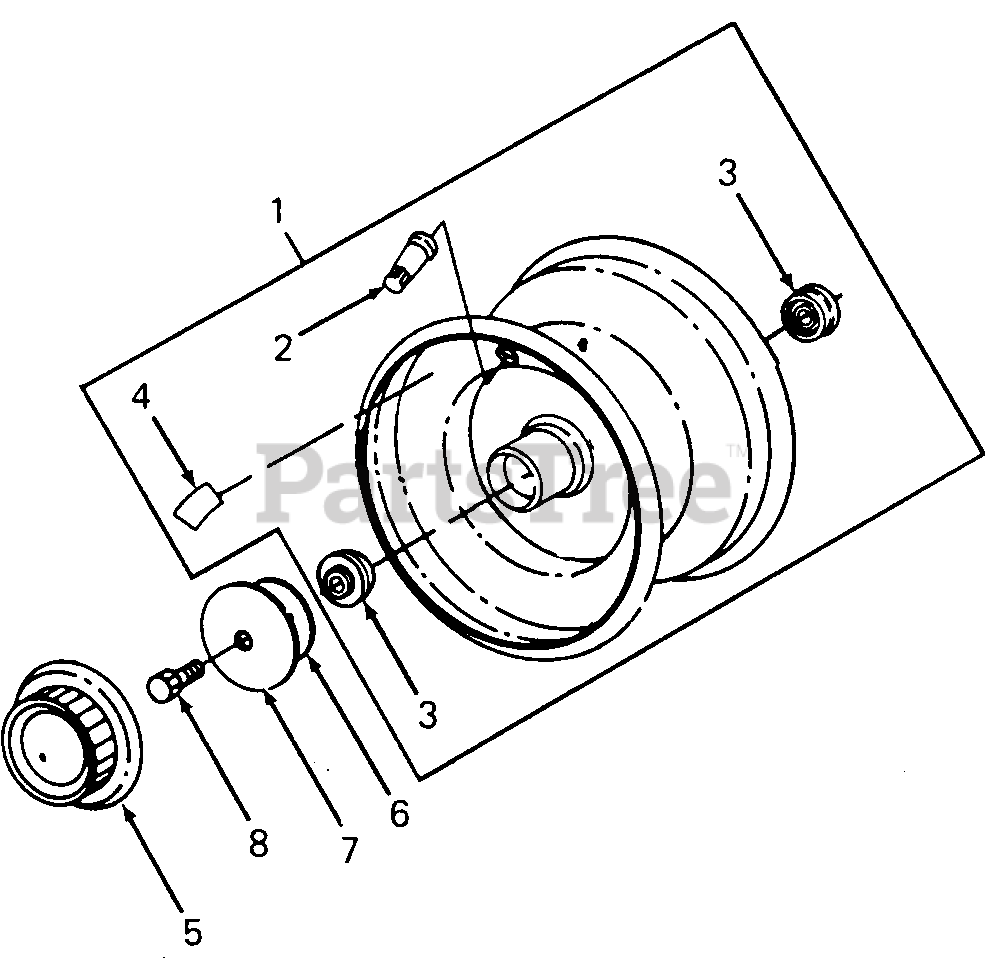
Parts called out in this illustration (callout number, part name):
1	Wheel Assy, Front
2	Valve, Tubeless Air
3	Bearing, Ball
4	Label, Inflation
5	Cap, Hub
6	Washer, Flat, .406 X 1.5 X .110 Thk
7	Washer, Flat, .406 X 1.92 X .06 Thk
8	Bolt, Hex Patch, 3/8-16 X .75 Lg GR5
